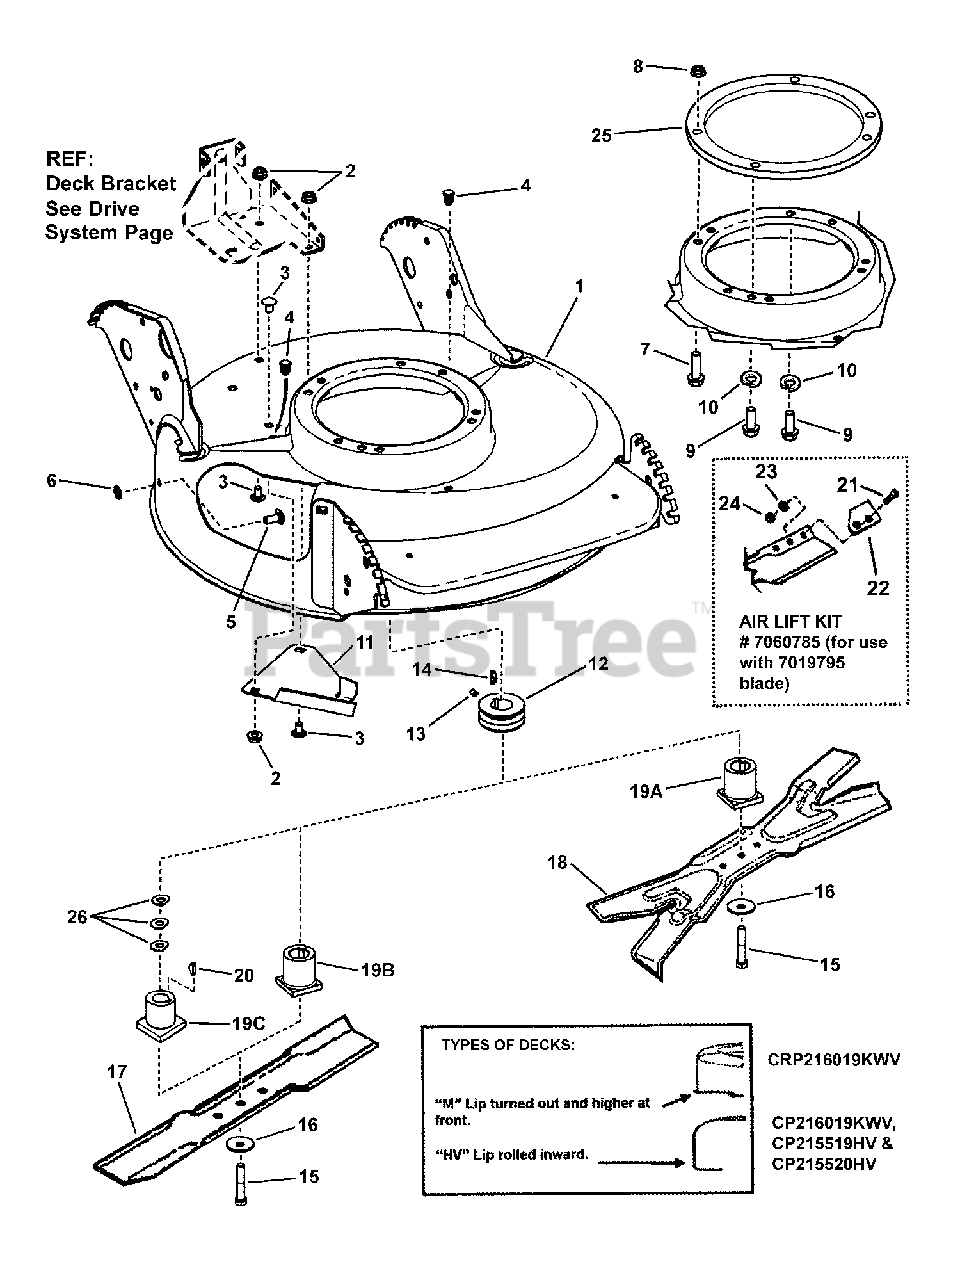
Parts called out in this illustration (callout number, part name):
1	* WELDMENT, Deck, 21" Non-Adjust Air
1	* WELDMENT, Deck, 21", S.P., Hi-Vac
2	NUT, 5/16-18 Hex Flange Lock GR 5
3	BOLT, 5/16-18 x 1/2", Short Neck Carriage, GR 5
4	PLUG, Hole, Polyethylene
5	BOLT, 5/16-18 x 3/4" Short Neck Carriage GR 5
6	RETAINER, 5/16" Bolt
7	BOLT, 5/16-18 x 1-1/2" Hex Flange Lock, GR5
8	NUT, 5/16-18 Hex Flange Lock, GR 5
9	SCREW, 5/16-24 x 1" Hex Head Cap GR 5
10	WASHER, .32 x .58 x .08 Split Lock
11	COVER, Belt
12	PULLEY- Engine (25mm I.D. x 2-1/8" O.D.)
12	PULLEY- Engine (1.085 I.D. x 2-1/8" O.D.)
13	SCREW, 5/16-18 x 5/16" Hex Socket Head
13	SCREW, 5/16-18 x 1/2" Hex Socket Head
14	KEY, Woodruff #HP-506 Hi-Pro
15	SCREW, 3/8-24 x 2" Hex Head Cap, GR 5
16	WASHER, Cone
17	BLADE, Cutter (Standard Lift)
18	BLADE, 21" Ninja (Quad Edge)
19A	** HUB, Blade Drive, 25mm I.D. RD 2 Position
19B	** HUB, Blade Drive, 25mm I.D.
19C	** HUB, Blade Drive, 7/8" I.D.
20	KEY, #505 Hi-Pro
21	SCREW, 5/16-24 x 21/32" Oval Head Machine
22	AIR LIFT
23	WASHER, 5/16" Internal Tooth Lock
24	NUT, 5/16-24 Hex, GR 5
25	RING, Engine Spacer
26	SPACER, .06 Blade Hub
